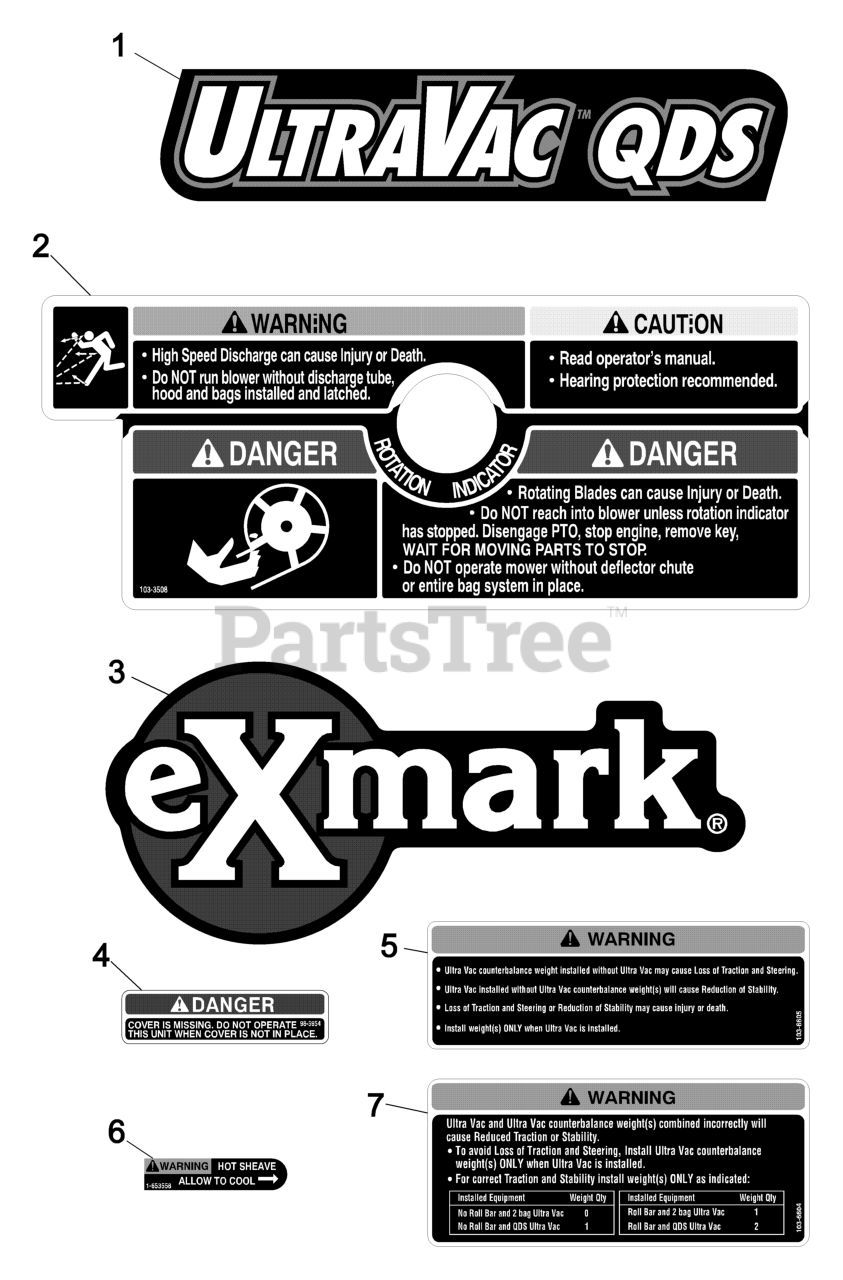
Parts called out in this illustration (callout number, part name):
1	DECAL, ULTRAVAC QDS
2	DECAL-WARNING
3	DECAL, EXMARK LOGO
4	DECAL-COVER, MISSING
5	DECAL,WEIGHT
6	DECAL-WARNING
7	DECAL,WEIGHT
